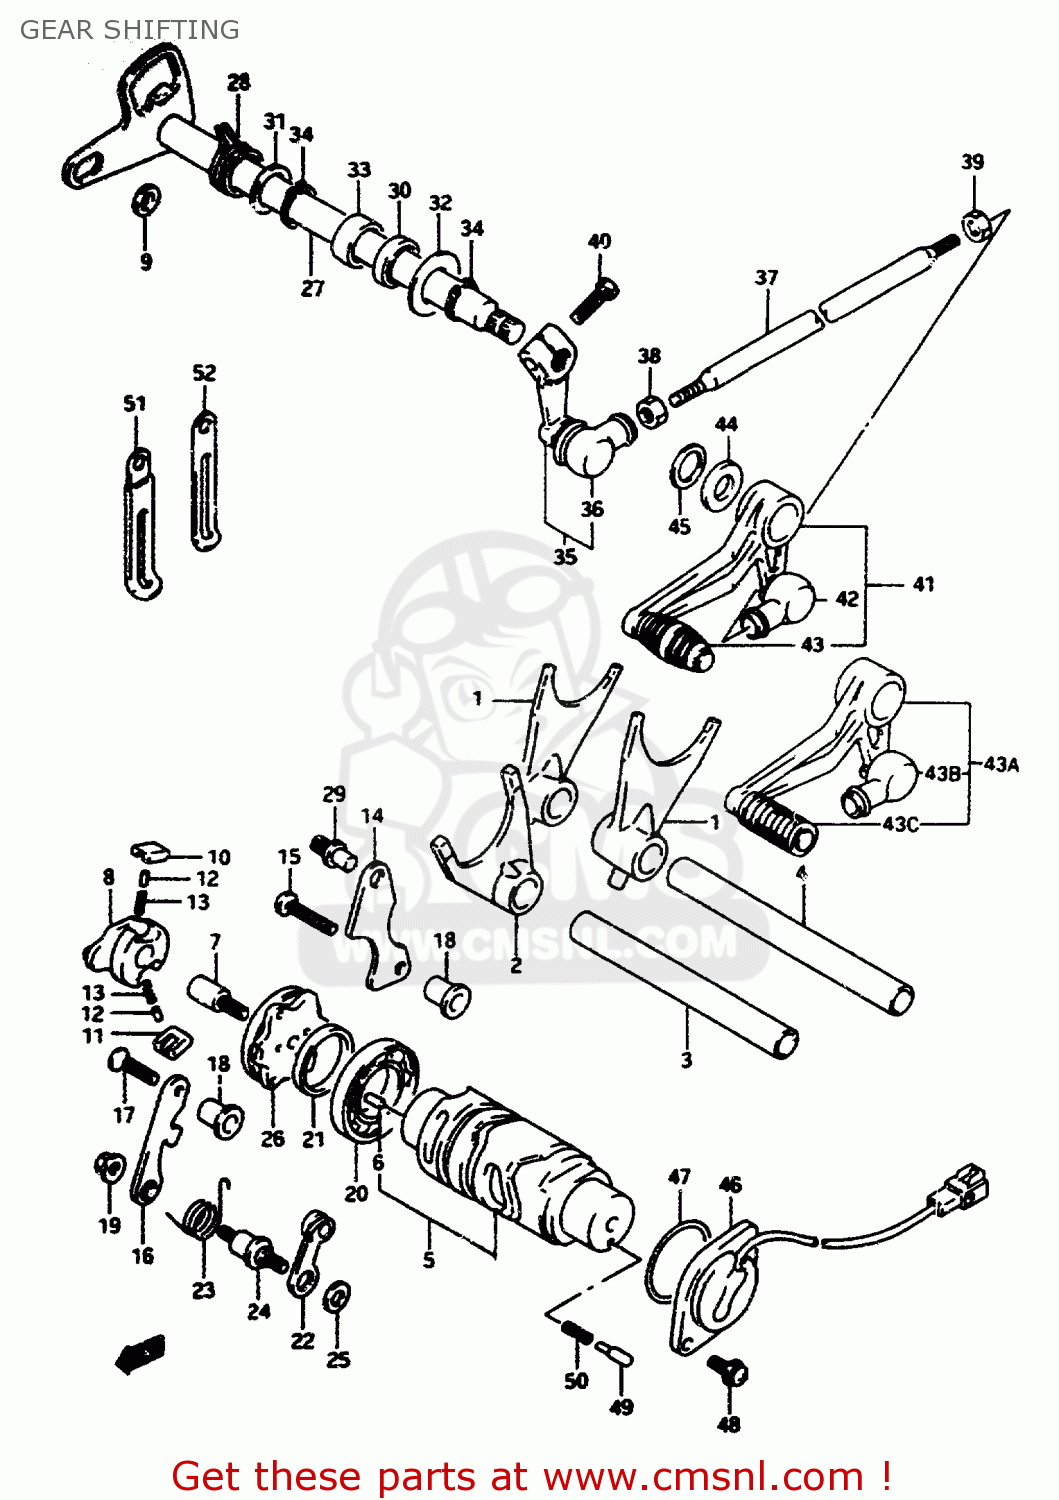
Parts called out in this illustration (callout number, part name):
1	FORK,GEAR SHIFT NO.1
2	FORK,GEAR SHIFT NO.3
3	SHAFT,GEAR SHIFT FORK
4	SHAFT,GEAR SHIFT FORK(L:128)
5	CAM,GEAR SHIFT
6	PIN
7	PIN,SHIFT CAM DRIVEN GEAR
8	SHIFTER,GEAR SHIFT CAM
9	SPACER(7X10X5)
10	PAWL,GEAR SHIFT NO.1
11	PAWL,GEAR SHIFT NO.2
12	PIN(5X8)
13	SPRING
14	LIFTER,GEAR SHIFT PAWL
15	SCREW 6X30
16	GUIDE,GEAR SHIFT CAM
17	SCREW
18	SPACER(6.1X10X16)
19	NUT
20	BEARING
21	WASHER(25X32X3)
22	STOPPER,GEAR SHIFT CAM
23	SPRING,STOPPER ARM
24	SUPPORT,CAM STOPPER ARM
25	WASHER
26	PLATE,GEAR SHIFT CAM
27	SHAFT,GEAR SHIFT
28	SPRING
29	STOPPER,GEAR SHIFT CAM
30	SEAL,OIL(14X22X6)
31	WASHER,THRUST
32	WASHER
33	BEARING(14X20X12)
34	CIRCLIP
35	ARM,GEAR SHIFT LINK
36	COVER,DUST
37	ROD,GEAR SHIFT LINK
38	NUT
39	NUT
40	BOLT
41	LEVER ASSEMBLY,GEAR SHIFTING
42	COVER,DUST
43	RUBBER,GEAR SHIFT PEDAL
43A	LEVER ASSY,GEAR SHIFT
43B	COVER,DUST
43C	RUBBER,GEAR SHIFT PEDAL
44	WASHER(14X27X4)
45	WASHER(18X24X1)
46	TERMINAL BASE ASSY,NEUTRAL
47	O RING(D:2.4,ID:36.5)
48	SCREW
49	PIN(5X15.5)
50	SPRING
51	CLAMP
52	CLAMP
